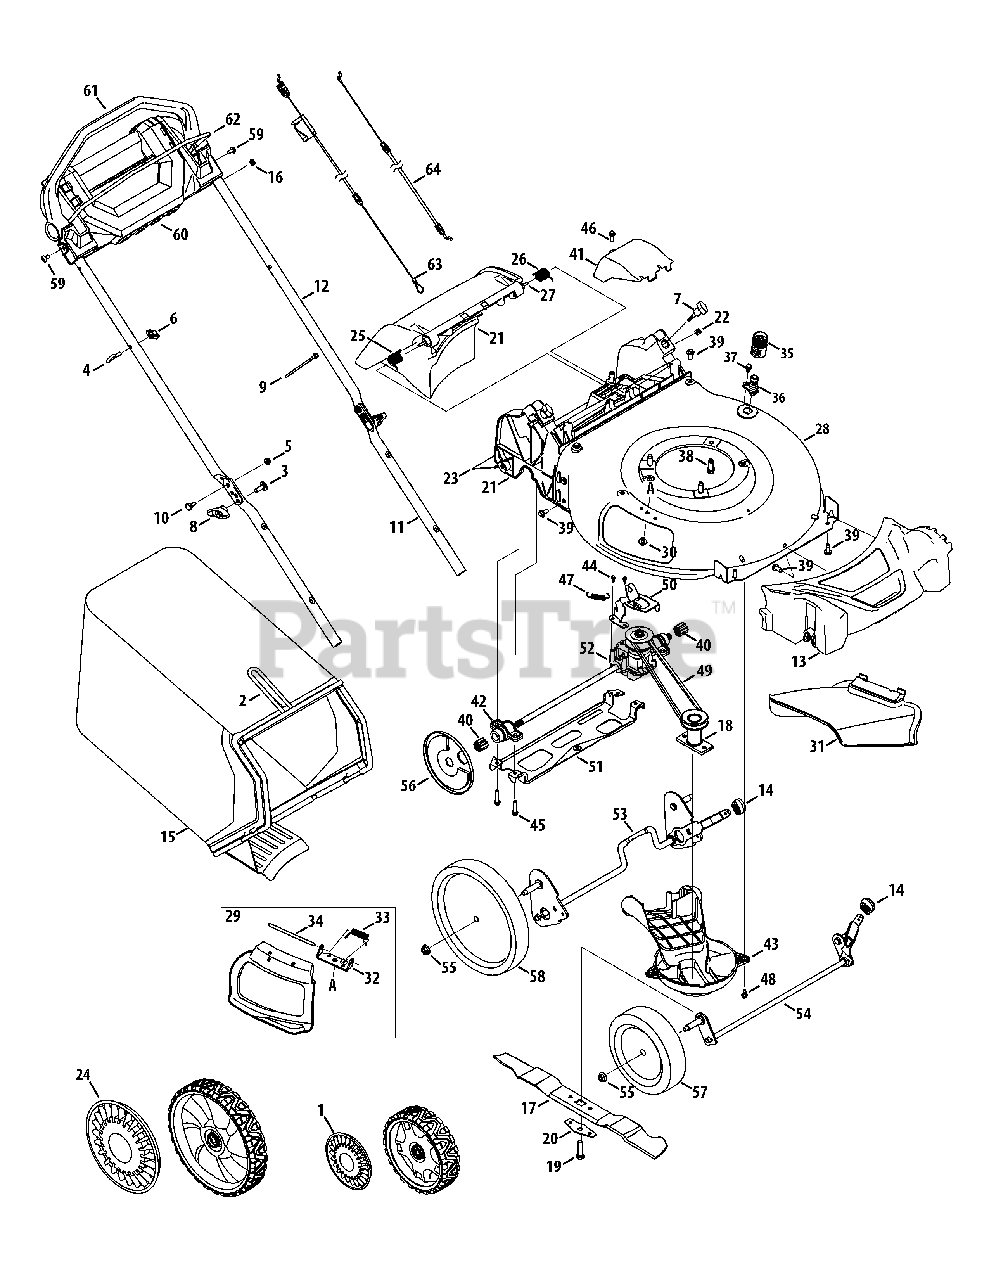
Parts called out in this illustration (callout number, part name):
1	Hubcap, 8", Grey
2	Grass Catcher Frame
3	Carriage Screw ,5/16-18
4	Rope Guide
5	Nut, Flange Lock, 1/4-20
7	Wing Nut
8	Wing Knob
9	Cable Tie
10	Shdr. Screw, .375 x .126 x 1/4-20
11	Lower Handle
12	Upper Handle
13	Front Cover
14	Adjustment Lever Knob
15	Grass Bag
16	Shoulder Spacer, .18 x .315 x .09
17	Mulching Blade
18	Blade Adapter
19	Screw, 3/8-24 x 1.50
20	Blade Bell Support
21	Rear Discharge Door Assembly
22	Nut, Sq., 1/4-20
23	Trail Shield
24	Hubcap, 11", Grey
25	Torsion Spring - RH
26	Torsion Spring - LH
27	Pivot Rod
29	Mulch Plug (Incl. 32-34)
31	Side Discharge Chute
32	Chute Deflector Bracket
33	Torsion Spring
34	Hinge Pin
35	Water Nozzle Adapter
36	Water Nozzle
37	Shoulder Screw, 1/4-20 x 0.50
38	Screw, tt, 3/8-16 x 1.00
39	Screw, 5/16-14 x .750
40	Spur Gear, 9T
41	Transmission Cover
42	Bearing Assembly
43	Engine Baffle
44	Screw, Hex Washer, .159 x .43
45	Screw, 1/4-15 x 1.25
46	Screw, 1/4-15 x .750
47	Exten. Spring, 2.405
48	Shoulder Screw, 1/4-20 x 0.50
49	V-Belt
50	Transmission Bracket
51	Rear Support Bracket
52	Transmission Assembly
53	Rear Axle Assembly
54	Front Axle Assembly
55	Flange Lock Nut, 3/8-16
56	Wheel Dust Cover
57	Front Wheel, 8 x2
58	Rear Wheel, 11 x 2
59	Screw, 1/4-14 x .625
60	Handle Console
61	Drive Handle
62	Blade Control
63	Drive Cable
64	Control Cable
